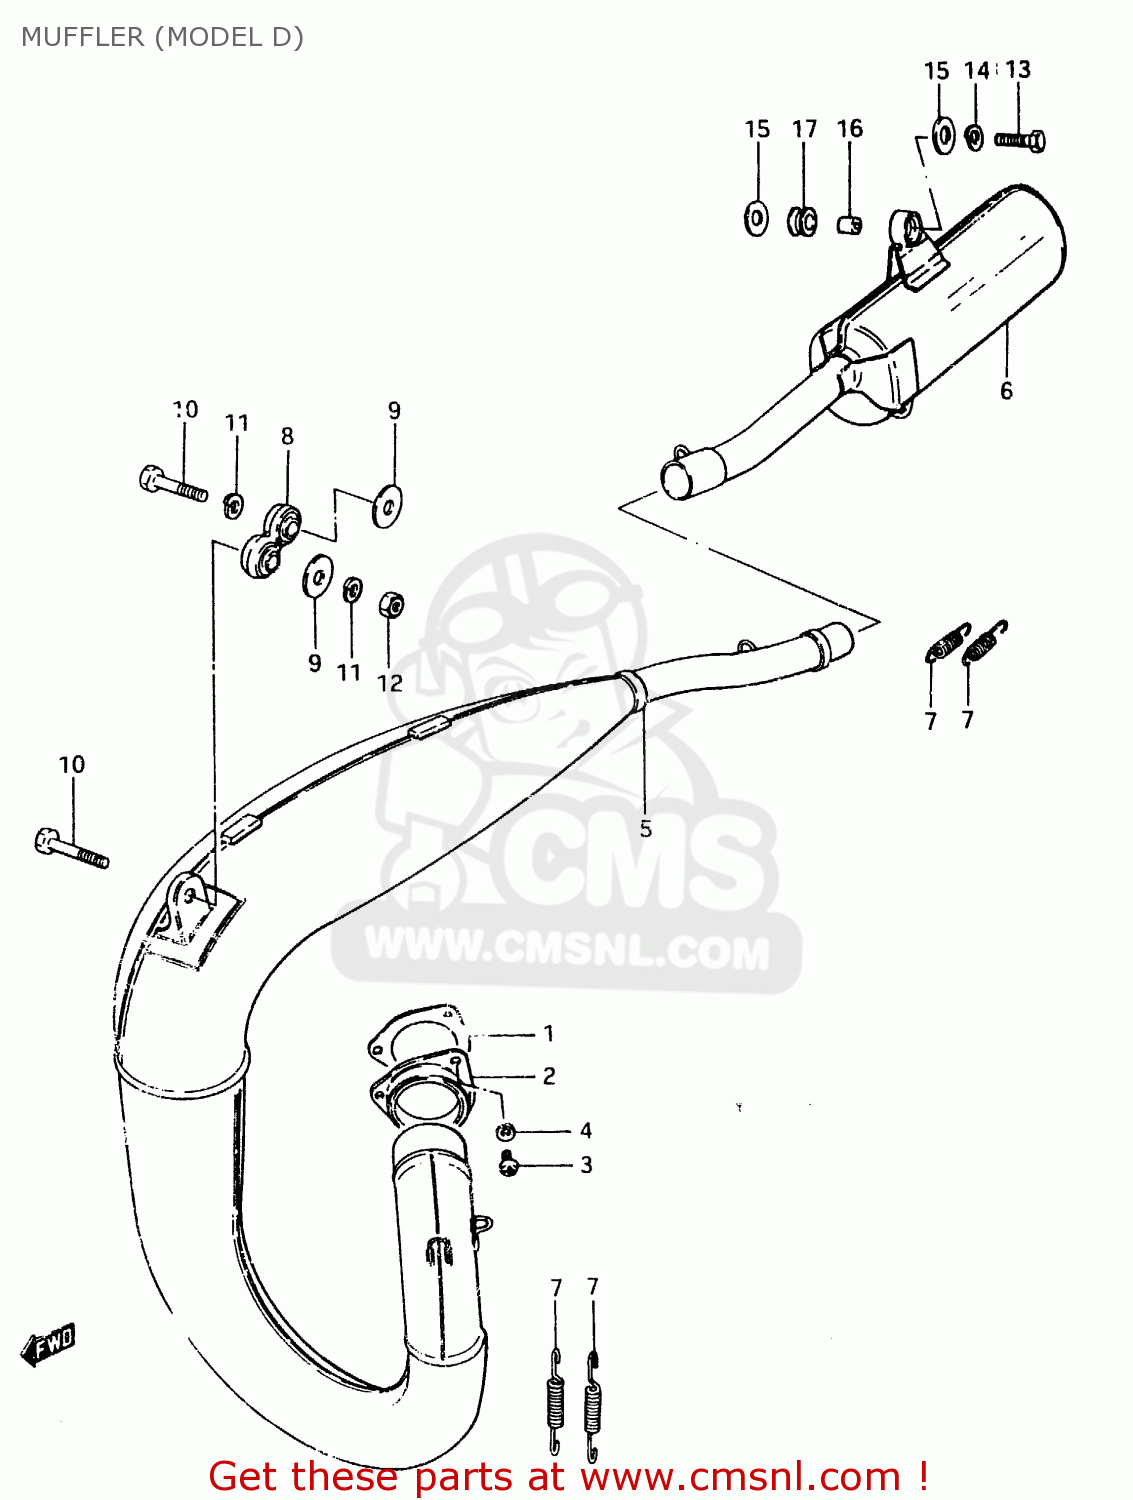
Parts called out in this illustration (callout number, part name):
1	GASKET,EXHAUST PIPE (MCA)
2	FLANGE,EXHAUST PIPE
3	SCREW
4	LOCK WASHER
5	BODY,MUFFLER
6	BODY,MUFFLER
7	SPRING
8	DAMPER,MUFFLER
9	WASHER
10	BOLT(8X32)
11	LOCK WASHER
12	NUT 8MM
13	BOLT(8X32)
14	LOCK WASHER
15	WASHER (8.5X29X1.6)
16	SPACER (8.6X12X17.5)
17	CUSHION
